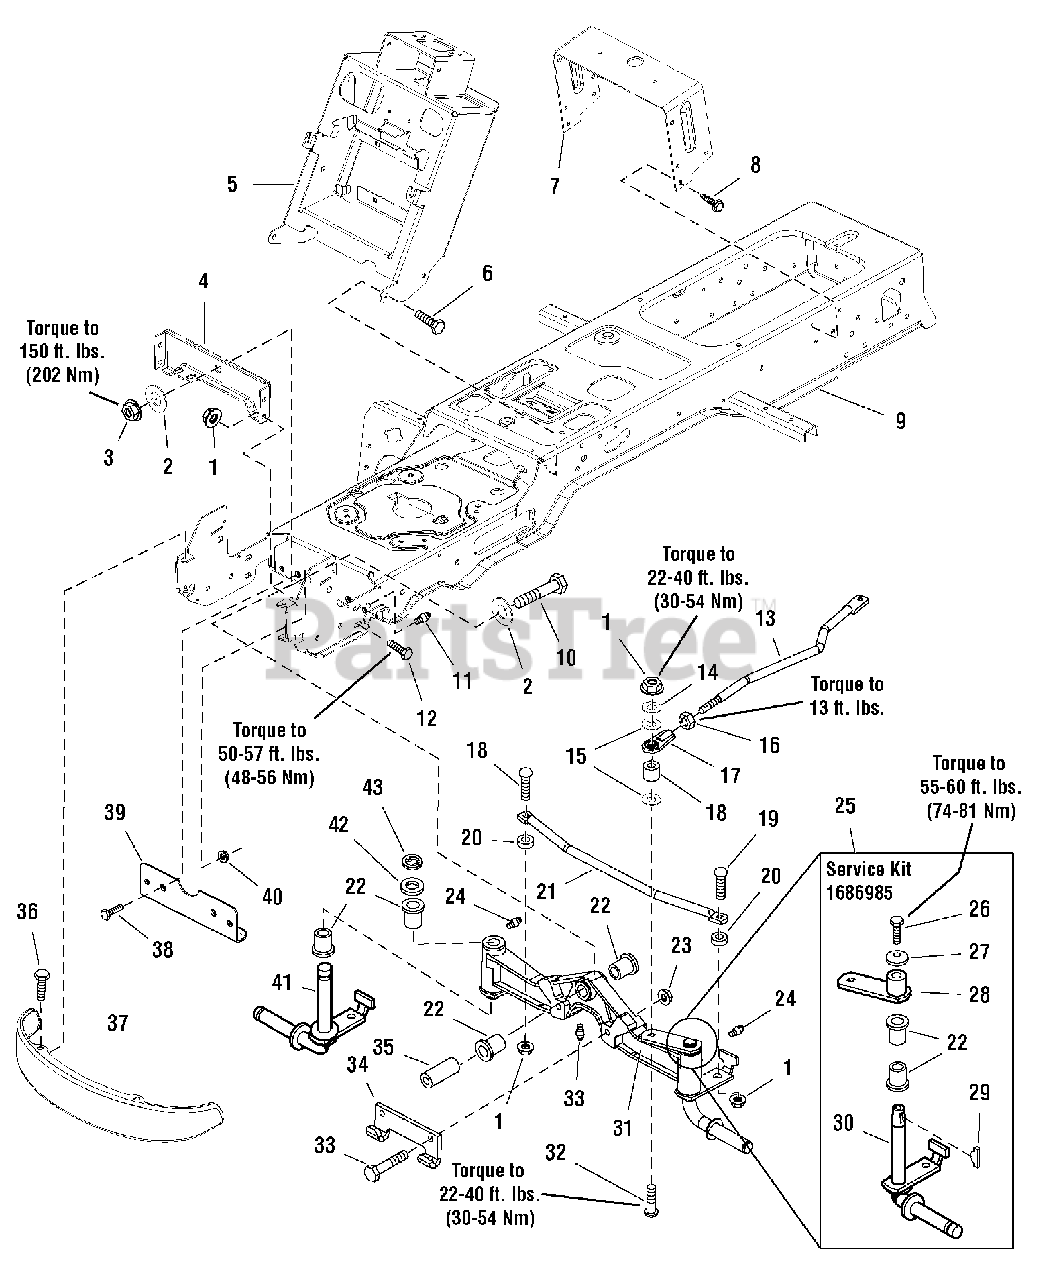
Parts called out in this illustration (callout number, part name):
1	NUT, Hex Flange Lock, 3/8-16
2	WASHER
3	NUT, Hex Flange, 5/8-11
4	PLATE, Axle
5	TOWER & SUPPORT ASSEMBLY
6	CAPSCREW, Hex Head Taptite, 3/8-16 x 3/4
7	SUPPORT
8	CAPSCREW, Hex Head Taptite, 5/16-18 x 3/4
9	FRAME ASSEMBLY
10	CAPSCREW, 5/8-11 x 3-1/2
11	FITTING, Grease for Wear Plate, 1/4-20, with Ball
12	CAPSCREW, Hex Head, Flange Lock, 3/8-16 x 3/4
13	LINK, Drag
14	WASHER
15	WASHER
16	NUT, Hex Jam, 1/2-20
17	JOINT, Ball
18	SPACER
19	CARRIAGE BOLT, 3/8-16 x 1
20	SPACER
21	ROD, Tie
22	BUSHING
23	NUT, Hex Flange Lock, 7/16-14
24	FITTING, Lube
25	SPINDLE REPLACEMENT KIT, LH (Includes Ref. Nos. 22, 26, 27,
26	CAPSCREW, 3/8-16 x 7/8, GR8
27	WASHER, Spring, 3/8
28	HUB & ARM ASSEMBLY
29	KEY, Woodruff
30	SPINDLE, LH
31	AXLE ASSEMBLY, w/ LH Spindle, Complete (Includes Ref. Nos. 2
32	CARRIAGE BOLT, 3/8-16 x 1-1/2
33	CAPSCREW, Hex Head, 7/16-14 x 2, GR8
34	HOOK, "J"
35	SPACER
36	SCREW, Torx Head, 5/16-18 x 7/8
37	BUMPER, Black, Steel, Standard
37	BUMPER, Chrome, Optional
38	CAPSCREW, Hex Whiz Lock, 5/16-18 x 3/4
39	PLATE, Axle Wear
40	NUT, Hex Falnge Whiz Lock, 5/16-18
41	SPINDLE, RH
42	WASHER
43	RETAINING RING
